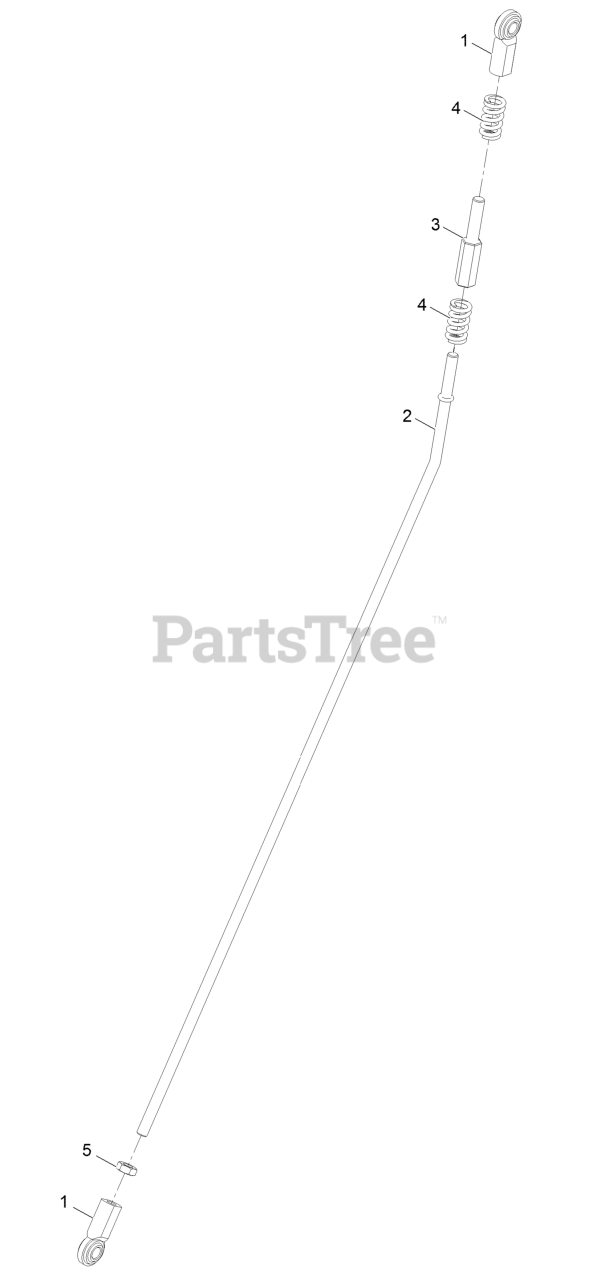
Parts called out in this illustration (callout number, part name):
1	Balljoint
2	Linkage-Motion
3	Rod-Adjustment
4	Spring-Compression
5	Nut-Jam 3/8-24
